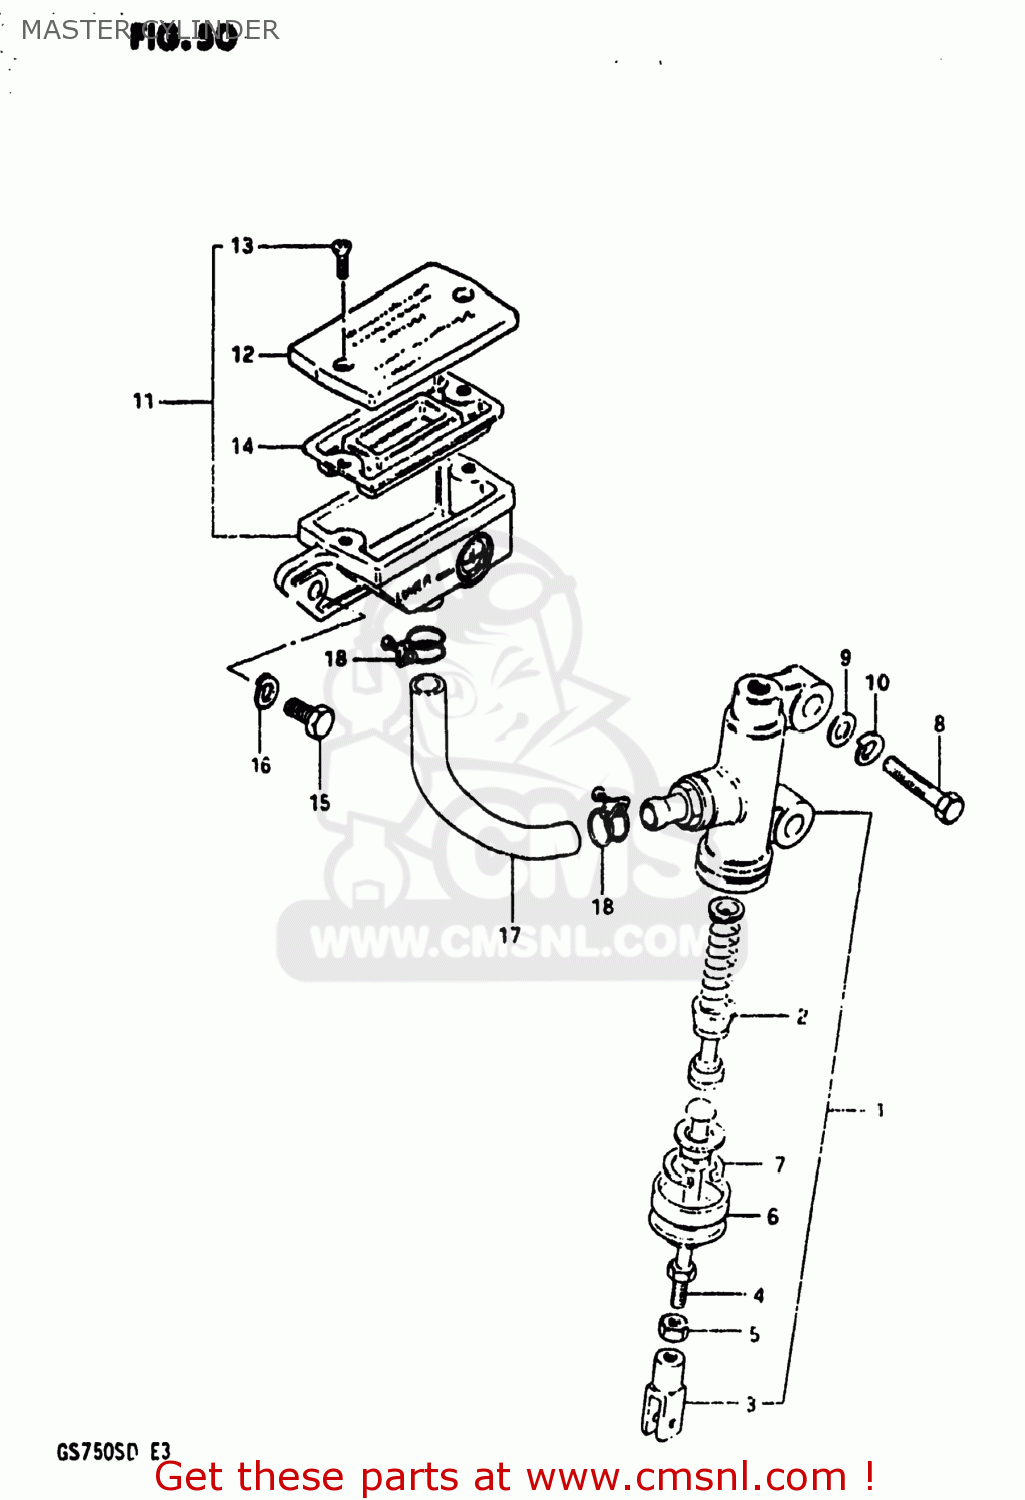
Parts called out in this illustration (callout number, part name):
1	CYLINDER ASSEMBLY,REAR MASTER
2	PISTON/CUP SET
3	YOKE
4	LOD,PUSH
5	NUT,MASTER CYLINDER
6	BOOT
7	CIRCLIP
8	BOLT (8X30)
9	WASHER
10	LOCK WASHER
11	TANK ASSEMBLY,RESERVOIR
12	CAP
13	SCREW
14	15
15	BOLT, UPPER
16	LOCK WASHER
17	HOSE,RESERVOIR TANK
18	CLAMP
